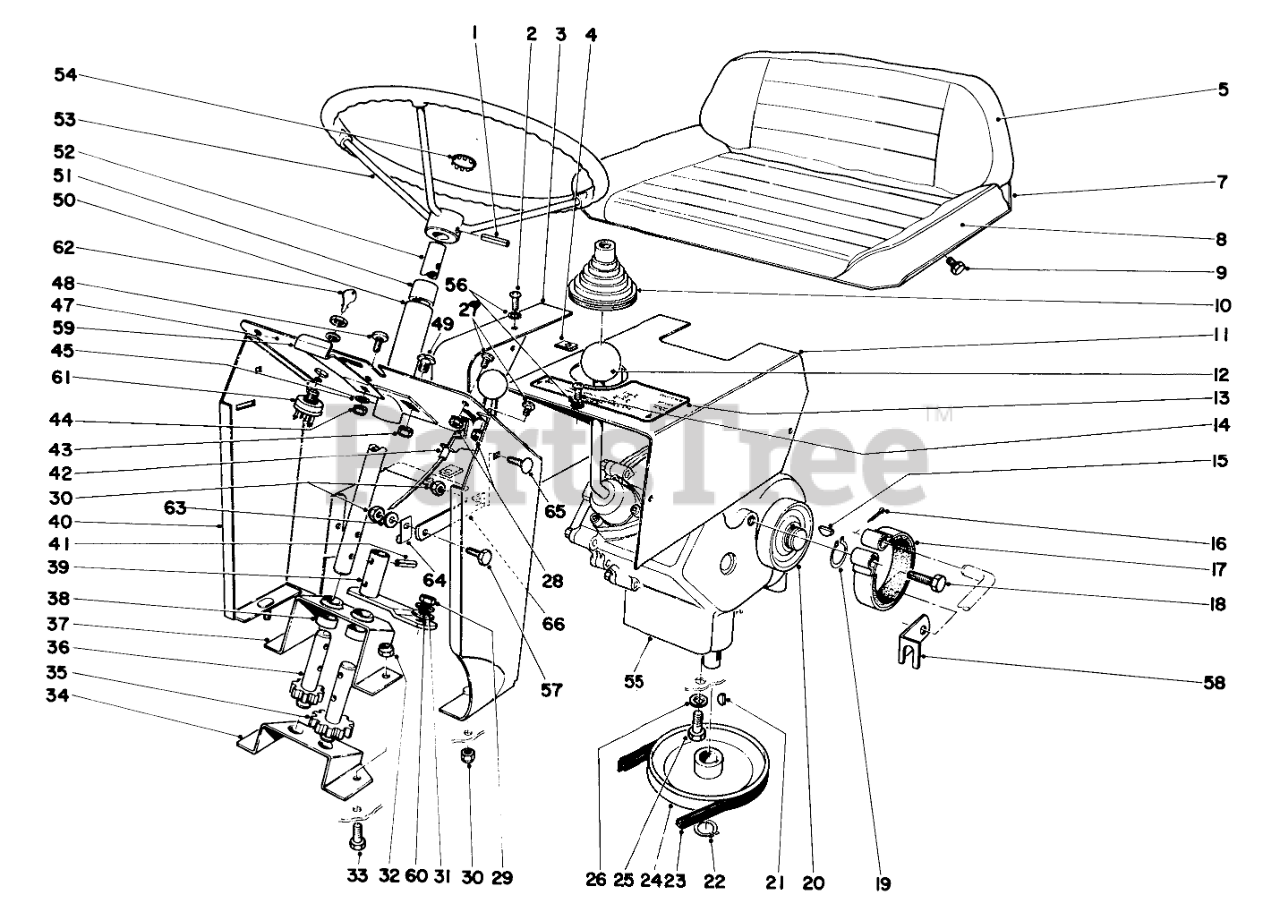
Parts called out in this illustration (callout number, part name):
1	PIN-ROLL
2	10-24 X 3/8 PAN HD SC
3	Chain Guard
4	NUT-CLIP,U
5	Cushion Back
7	Frame Seat
8	Cushion Seat
9	Screw
10	Boot Shift Lever
11	Cover Transmission
13	Decal Shift Pattern
14	10-24 X 3/8 PAN HD SC
15	KEY-WOODRUFF
16	PIN-COTTER
17	Brake Band
18	He Ha. Screw
19	Ring-Snap
20	Brake Drum
21	KEY-WOODRUFF
22	RING-SNAP, EXTERNAL
23	TRANS TO ENGINE BELT
24	PULLEY
25	SCREW-HH
26	WASHER-LOCK/SP
28	NUT-KEPS
29	NUT-HEX
30	NUT-LOCK, CONE
31	WASHER-LOCK
32	NUT-LOCK, CONE
33	SCREW-HH
34	Bracket Steering
35	Steering Gear
36	Pinion Gear
37	Support Steering
38	Spacer
39	Steering Arm
40	Rear Hood Support (Recoil)
41	PIN-ROLL, SLOTTED
42	Throttle Control
43	NUT-LOCK, CONE
44	NUT-LOCK, CONE
45	WASHER-FLAT
47	Decal Control Panel (Recoil)
48	Carriage Bolt
49	Truss Head Screw
50	Steering Tube Assy. (Incl. Ref. No. 51)
51	BUSHING
52	Shaft Steering
53	Steering Wheel
55	Transmission
56	WASHER-LOCK, EXT
57	SCREW-HH
58	Retainer Brake Rod
59	Hood Latch
60	WASHER-FLAT
61	STARTER SWITCH
62	Key
63	WASHER-FLAT
65	SCREW-CARRIAGE
66	Hanger Throttle Control
